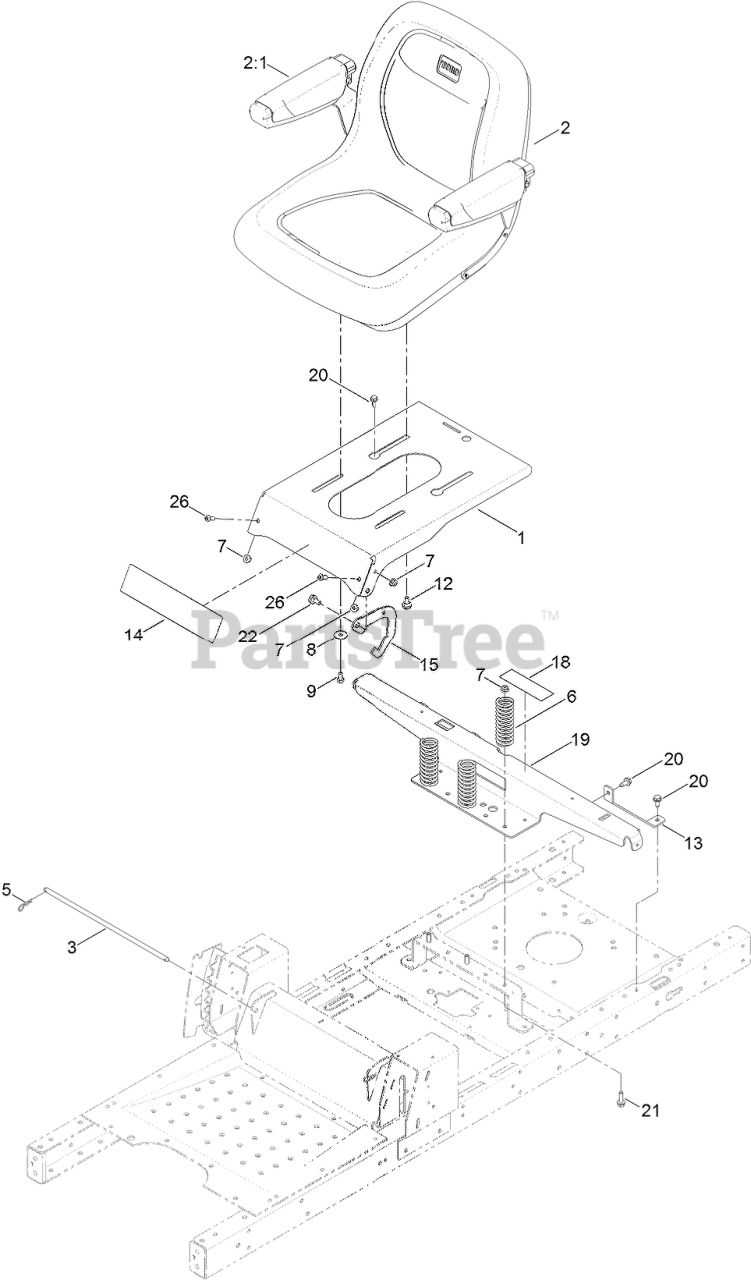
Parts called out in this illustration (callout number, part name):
1	PAN-SEAT
2	SEAT-18 Inch
3	ROD-PIVOT, NARROW
5	PIN-COTTER
6	SPRING-COMPRESSION
7	NUT-HF, NI
8	WASHER-PIVOT
9	SCREW-HH
12	BOLT-SHOULDER
13	SUPPORT-TANK, REAR
14	DECAL-TIMECUTTER
15	LATCH-SEAT
18	DECAL-SERVICE, CE
19	SUPPORT-POD
20	SCREW-HWHTF
21	SCREW-HHF
22	BOLT-SHOULDER
26	SCREW-HSBH
